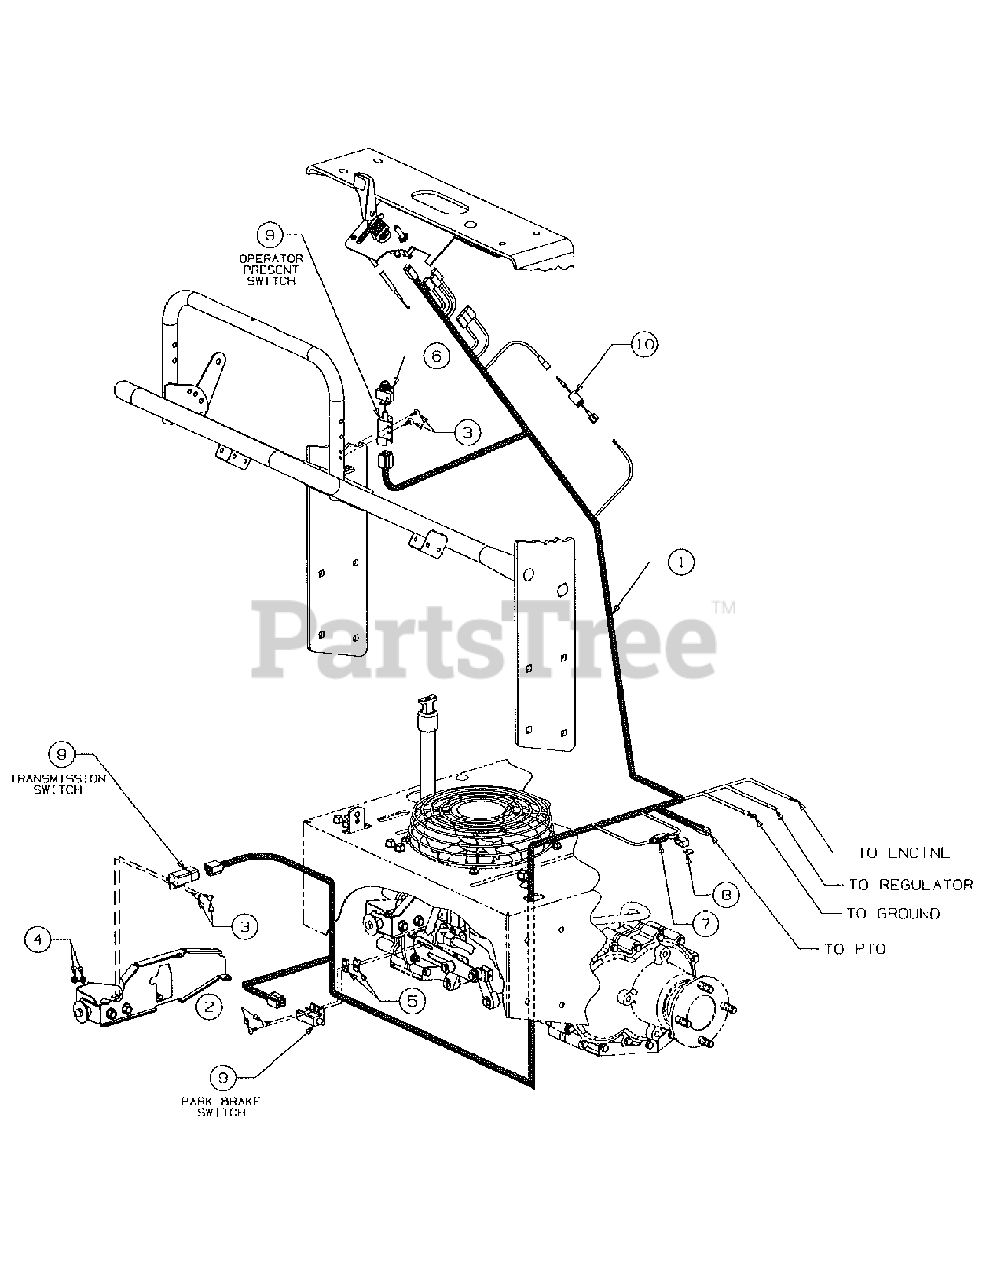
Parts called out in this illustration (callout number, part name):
2	Screw, Truss Mach, #10-24 x .50
3	Screw, Pan Hd Cutting, #10-24 x .75
4	Nut, Hex Lock, #10-24
5	Nut, Speed
6	Cover, Protective
7	Holder, Inline Fuse
8	Fuse, 20 Amp Mini
9	Switch, Double Poled Plunger
10	Capacitor Clutch
